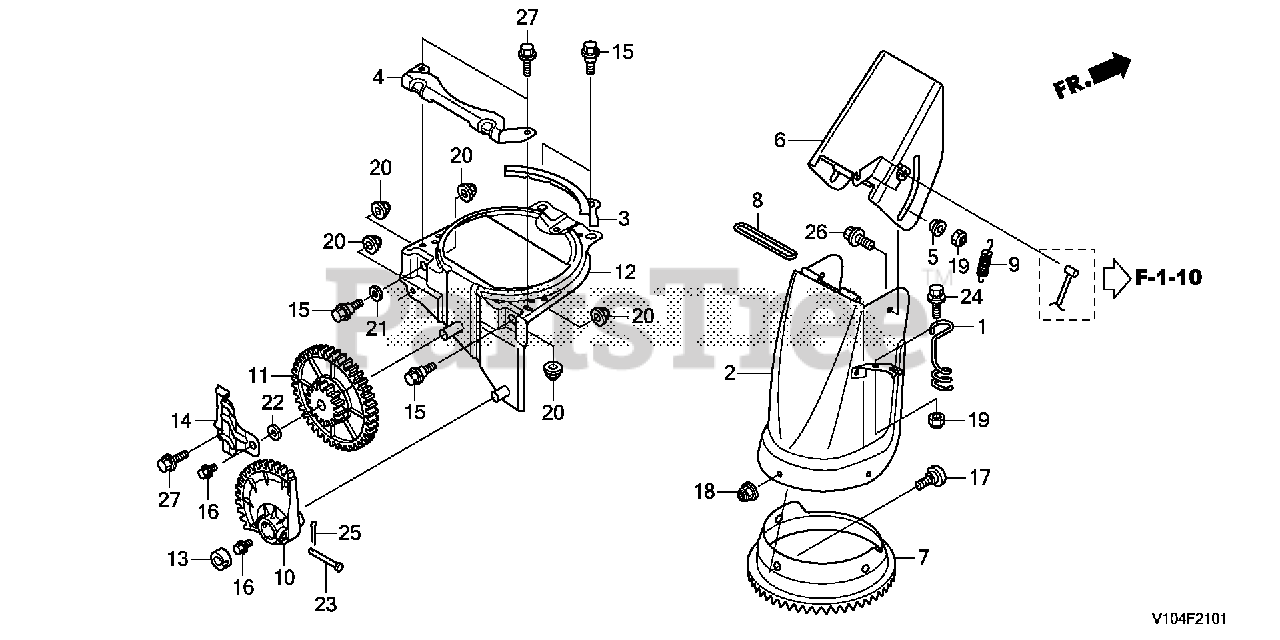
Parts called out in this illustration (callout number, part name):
1	HOLDER, GUIDE CABLE
3	PLATE, FR. CHUTE
4	PLATE, RR. CHUTE
5	COLLAR, CHUTE GUIDE
6	GUIDE, CHUTE
7	BUSH, CHUTE
8	PIN, CHUTE GUIDE
9	SPRING, CHUTE
10	GEAR, CHUTE DRIVE
11	GEAR, CHUTE DRIVEN
12	RECEIVER, CHUTE
13	SPACER, CONTROL ROD
14	PLATE, HEAT GUARD
15	BOLT, CHUTE SETTING
16	BOLT, WHEEL
17	BOLT, CHUTE SETTING
18	NUT, NYLON LOCK (6MM)
19	NUT, NYLON LOCK (6MM)
20	NUT, SELF-LOCK (6MM)
21	WASHER (9MM)
22	WASHER (8.5MM)
23	PIN (6X50)
24	BOLT-WASHER (6X16)
25	PIN, COTTER (1.6X12)
26	BOLT, FLANGE (6X12) Use up to Engine SN 1543277.
27	BOLT, FLANGE (6X14)
